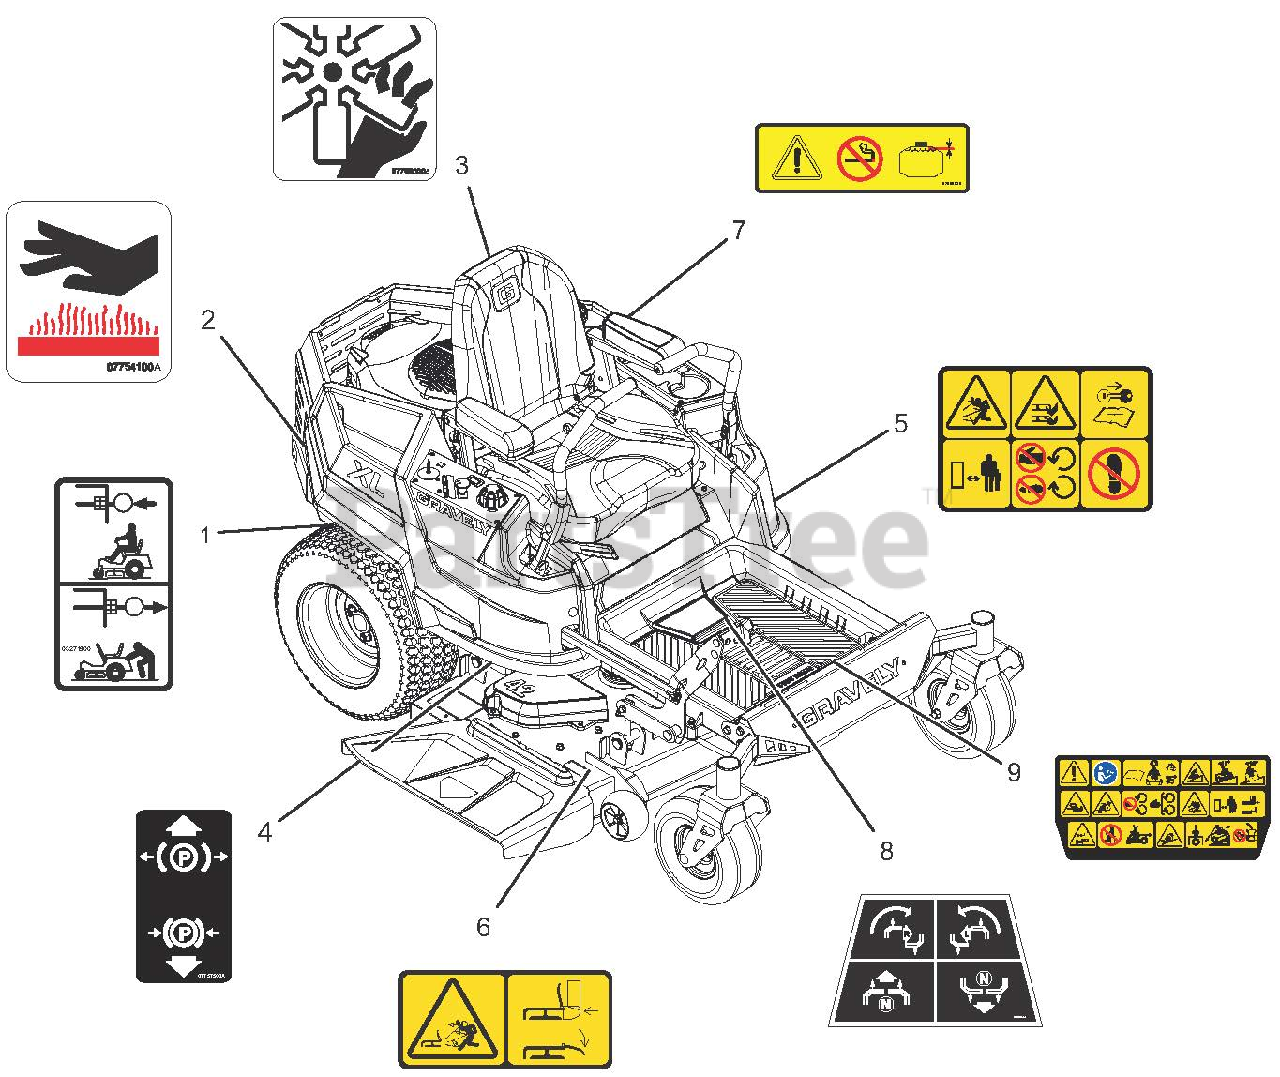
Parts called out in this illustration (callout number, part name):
1	DECAL, TRANSMISSION DISCONNECT
2	DECAL, HOT SURFACE
3	DECAL, DANGER FAN
4	DECAL, PARKING BRAKE LEVER
5	DECAL, SAFETY - MOWER DECK
6	DECAL, SAFETY - DECK GUARDING
7	DECAL-FUEL, WARNING
8	DECAL, STEERING
9	DECAL, MAIN SAFETY
